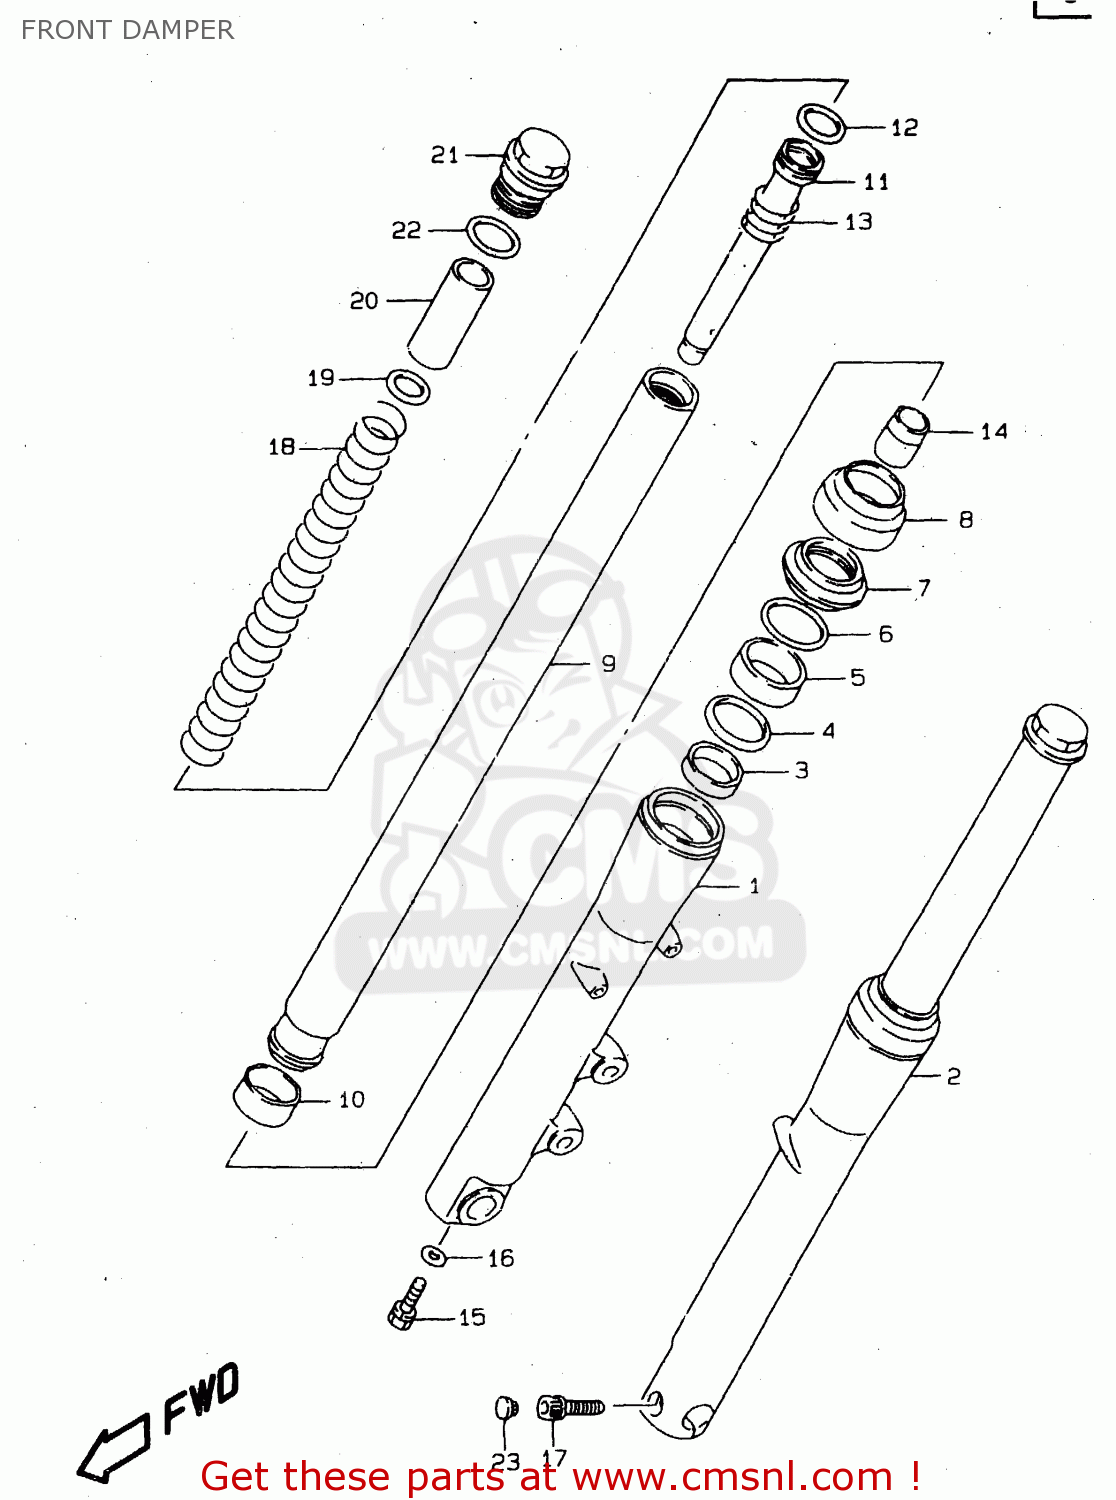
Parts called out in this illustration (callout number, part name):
1	TUBE,OUTER RH
2	TUBE,OUTER LH
3	BUSH,GUIDE
4	SPACER,SEAL
5	SEAL,OIL
6	RING,OIL SEAL STOPPER
7	SEAL,DUST
8	COVER,CASE
9	TUBE,INNER
10	BUSH,SLIDE
11	PIPE,SEAT
12	RING,PISTON
13	SPRING,REBOUND
14	PIECE,OIL LOCK
15	BOLT(8X27)
16	GASKET (NAS)
17	BOLT
18	SPRING
19	WASHER,SPRING
20	COLLAR,SPRING
21	BOLT,FORK
22	O RING
23	CAP(OD:14.5)
